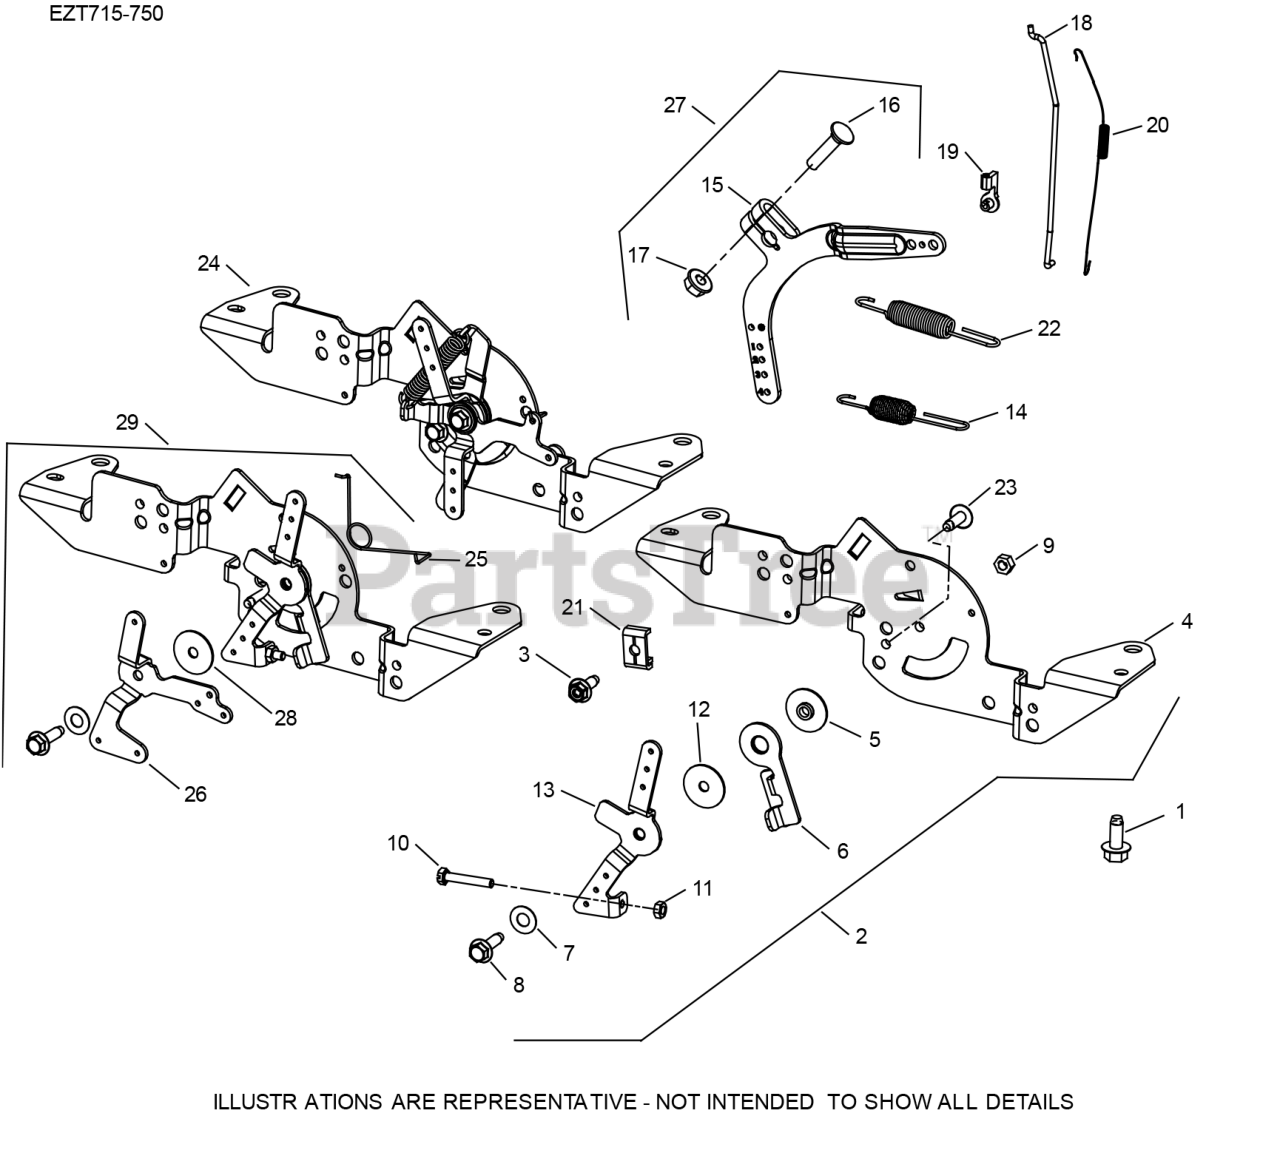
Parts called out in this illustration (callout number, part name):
1	SCREW-THREAD FORMI
2	SPEED CONTROL ASSEMBLY
3	THREAD FORMING SCREW
4	SPEED CONTROL BRACKET
5	SPACER-CONTROL ASSEMBLY
6	LEVER-THROTTLE ACT
8	THREAD FORMING SCREW
13	LEVER-THROTTLE CON
15	LEVER-GOVERNOR ASSEMBLY
16	BOLT-RD HD SQ NECK
17	HEX FLANGE NUT
18	THROTTLE LINKAGE
19	BUSHING-RETAINING
20	LINKAGE SPRING
22	GOVERNOR SPRING
